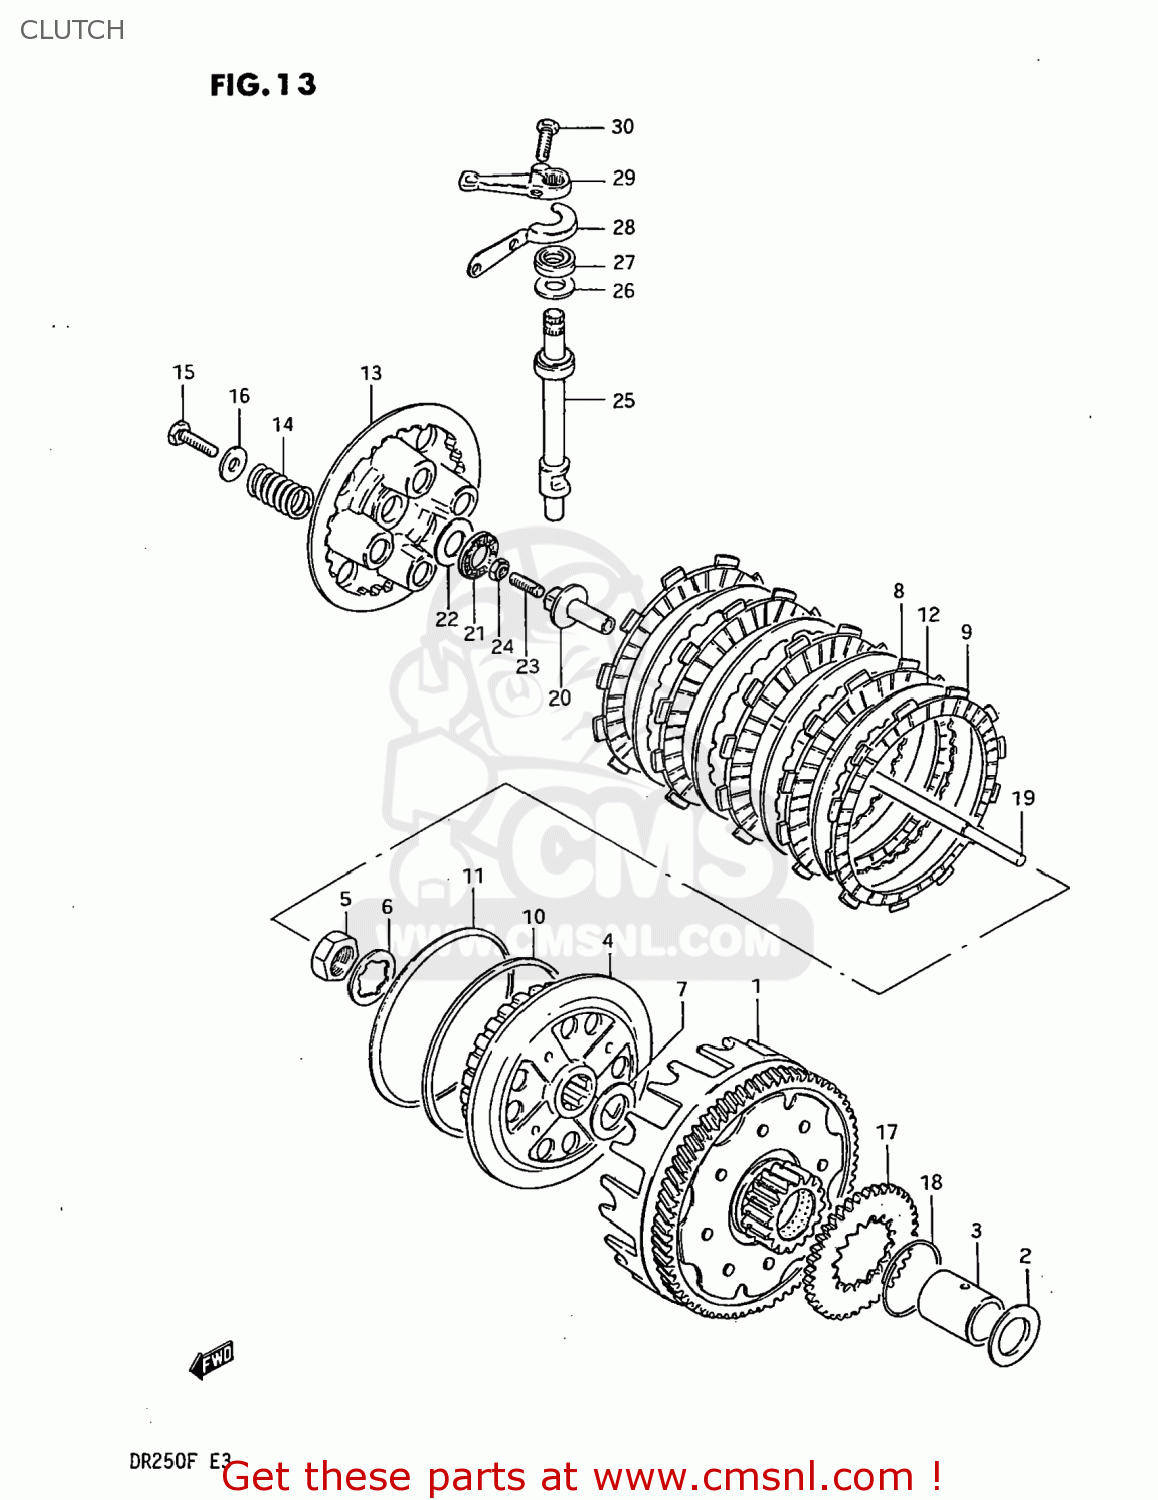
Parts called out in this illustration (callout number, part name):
1	GEAR ASSEMBLY,PRIMARY DRIVE
2	WASHER
3	SPACER(22X28X37.5)
4	HUB,CLUTCH SLEEVE
5	NUT
6	WASHER,LOCK
7	WASHER
8	PLATE,CLUTCH DRIVE (MCA)
9	PLATE,CLUTCH DRIVE
10	SEAT,WAVE WASHER(T:1.4)
11	WASHER
12	PLATE,CLUTCH DRIVEN
13	DISC,CLUTCH PRESSURE
14	SPRING
15	BOLT, UPPER
16	WASHER
17	GEAR,OIL PUMP DRIVE
18	CIRCLIP
19	ROD,CLUTCH PUSH
20	PIECE,CLUTCH PUSH
21	BEARING(15X28X2)
22	WASHER
23	SCREW(6X25)
24	NUT 6MM
25	CAMSHAFT,CLUTCH RELEASE
26	WASHER (14.2X22X1)
27	OIL SEAL
28	PLATE,RELEASE CAM SHAFT
29	ARM,CLUTCH RELEASE
30	BOLT
